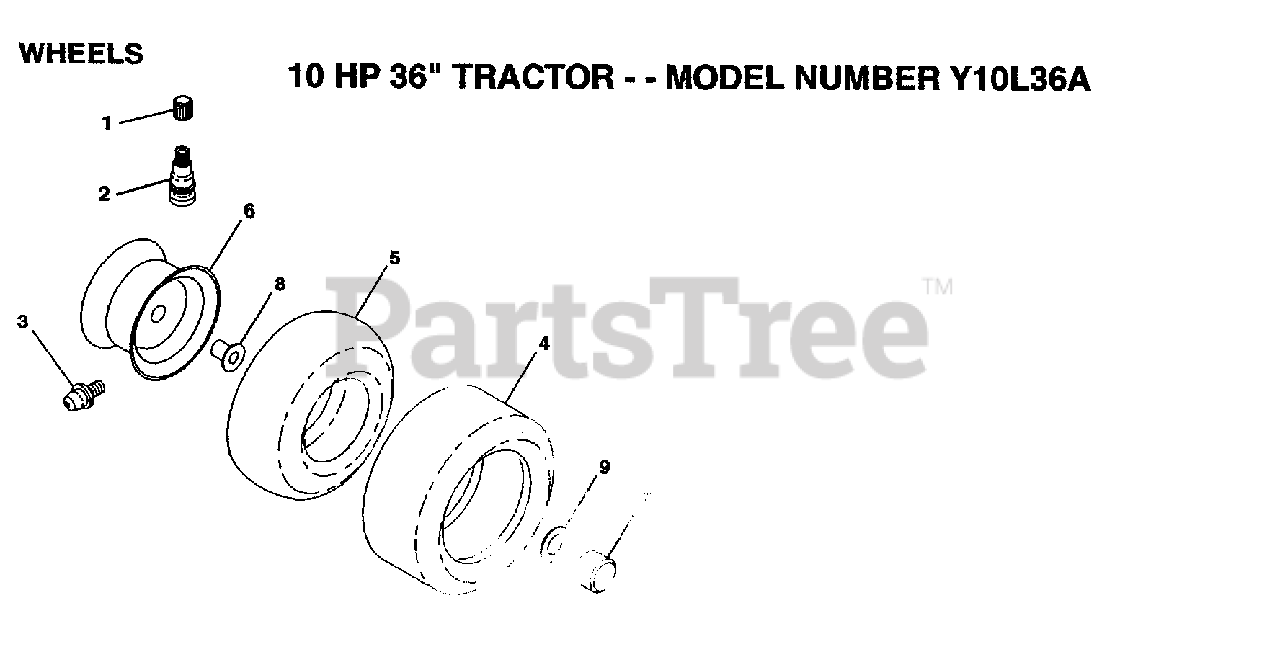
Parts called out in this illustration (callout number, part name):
1	VALVE CAP
2	VALVE STEM LT
3	FITTING LT
5	TUBE.5.3/4.5/6
7	HUB CAP
8	"FLANGE, BEARING"
9	WASHER
